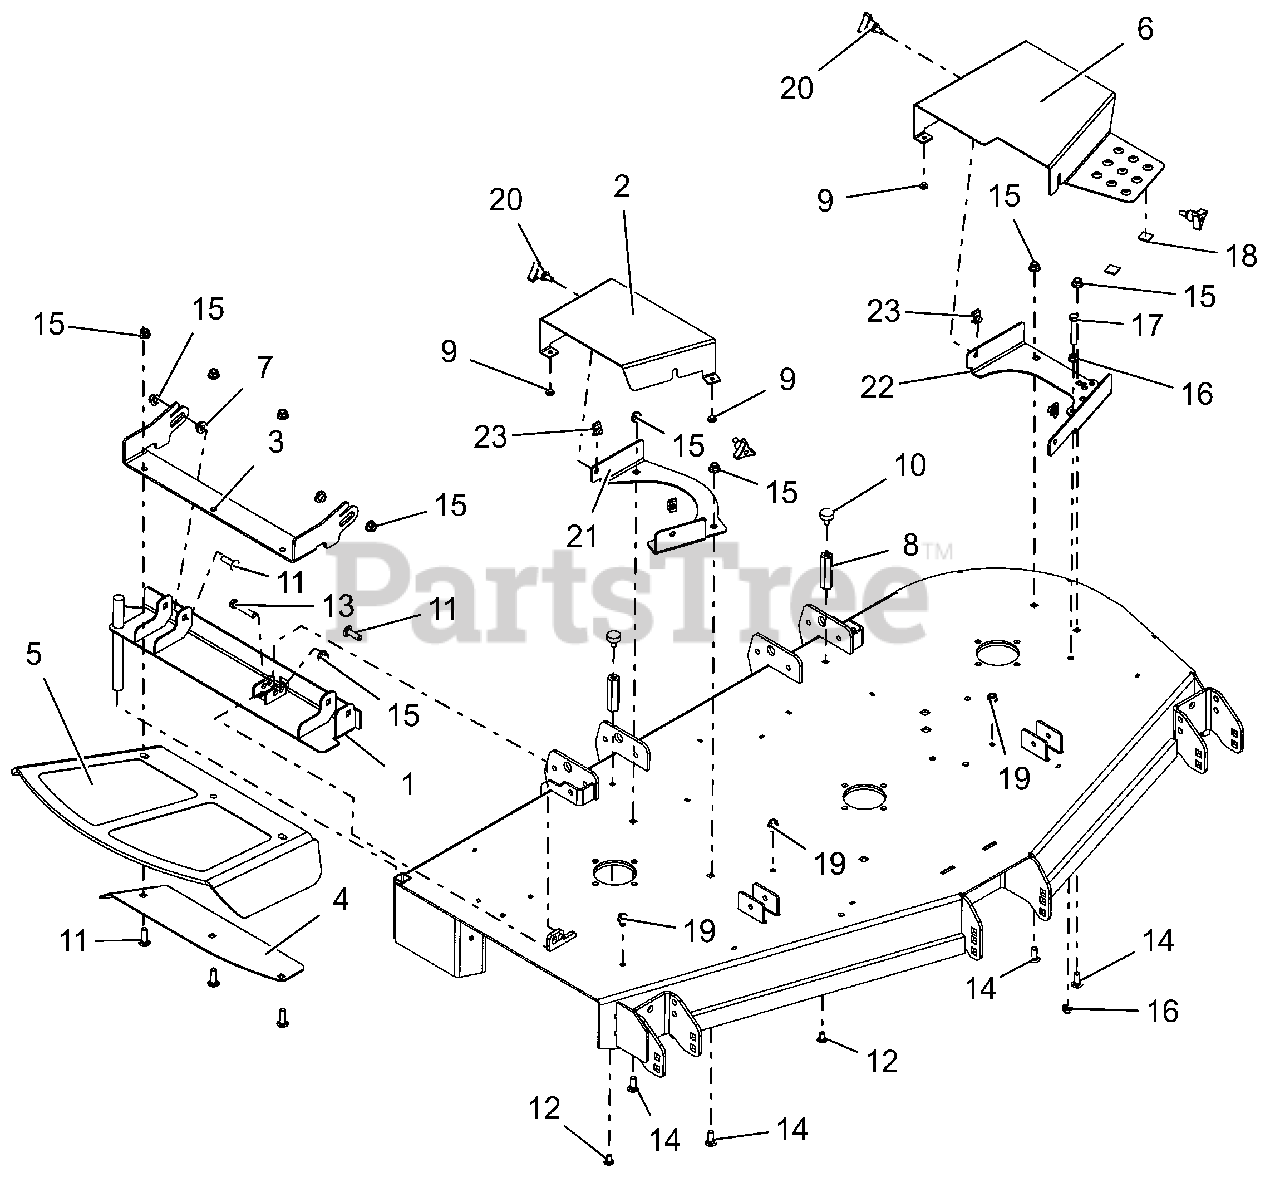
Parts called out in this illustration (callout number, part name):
1	48-60 DISCH CHT MTG WMT W/SAFE
2	PT148-152 DECK RH BELT GRD-RED
3	48-60" CHUTE MTG BRKT - RED
4	48-60 DISCH CHUTE CLMP PLT-RED
5	CHUTE,48-60" FRMD RUBBER DISCH
6	PT100 DECK LH BELT GUARD - RED
7	BSHG-FLG .385X.500X.875X.406
8	NUT, COUPLING .31-18 2.75 LG
9	BUMPER GROMMET
10	BUMPER, RUBBER
11	@BLT-RHDSSQNK .38-16X1.25 G5YZ
12	BLT-RDHDSQSHNK.31-18X.62 YZ-LK
13	@BLT-HEX .38-16X2.00 GR5 YWZC
14	@BLT-RDHDSQNK .38-16X1.00 G5YZ
15	@NUT-LK-NYL-FLG .38-16 YWZC
16	@NUT-SPNLK-FLG .375-16 YWZC
17	@BLT-HEX .38-16X2.25 GR5 YWZC
19	@SCR-TAP .38-16X.50 HWH TR YWZ
20	KNOB,WING STUD 5/16-18 X .75
21	BRKT, BELT GUARD RH MOUNTING (RED)
22	BRKT, BELT GUARD LH (RED)
23	NUT-CLIP RETAINER 5/16-18X.56
